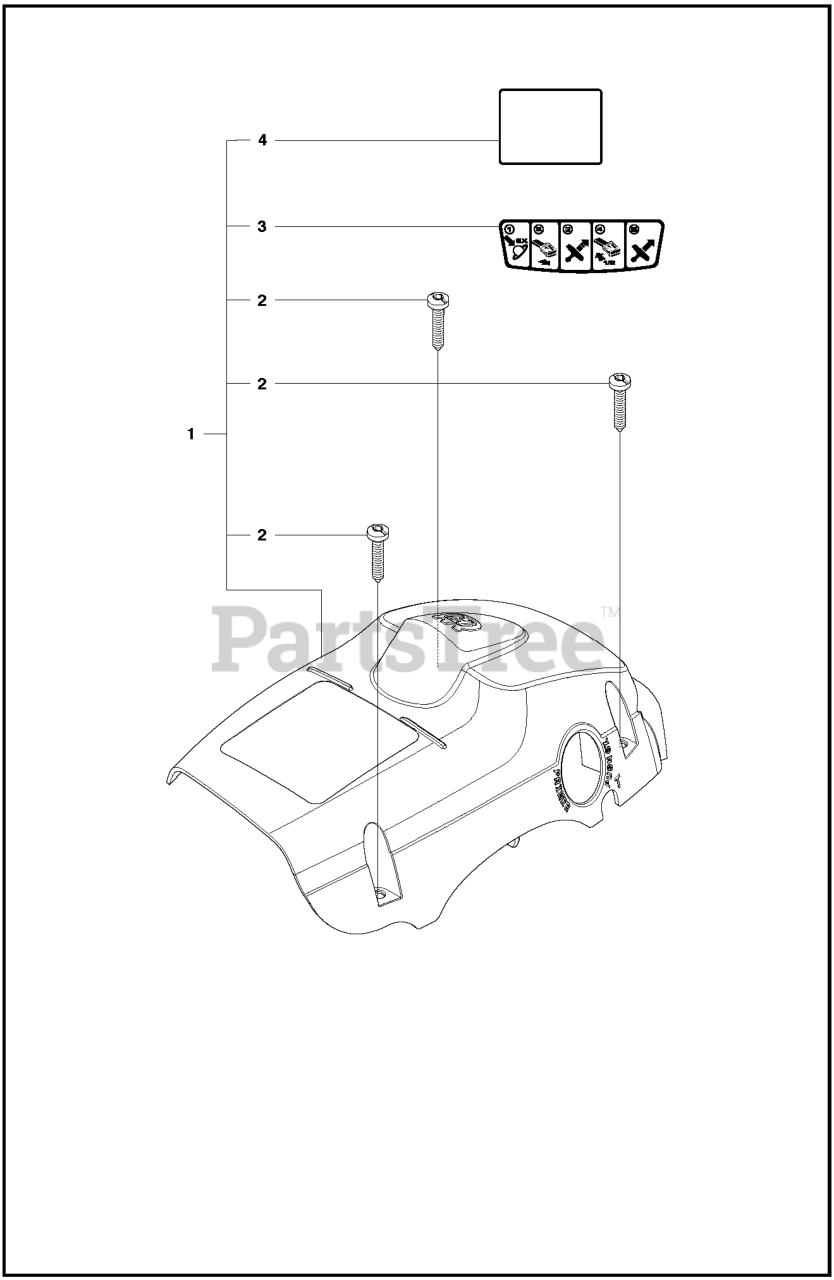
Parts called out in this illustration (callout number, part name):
1	KIT CYLINDER SHIELD
2	SCREW
3	DECAL
4	WARNING SIGN
NI	KIT CHASSIS BRASS INSERTS(3EA)
